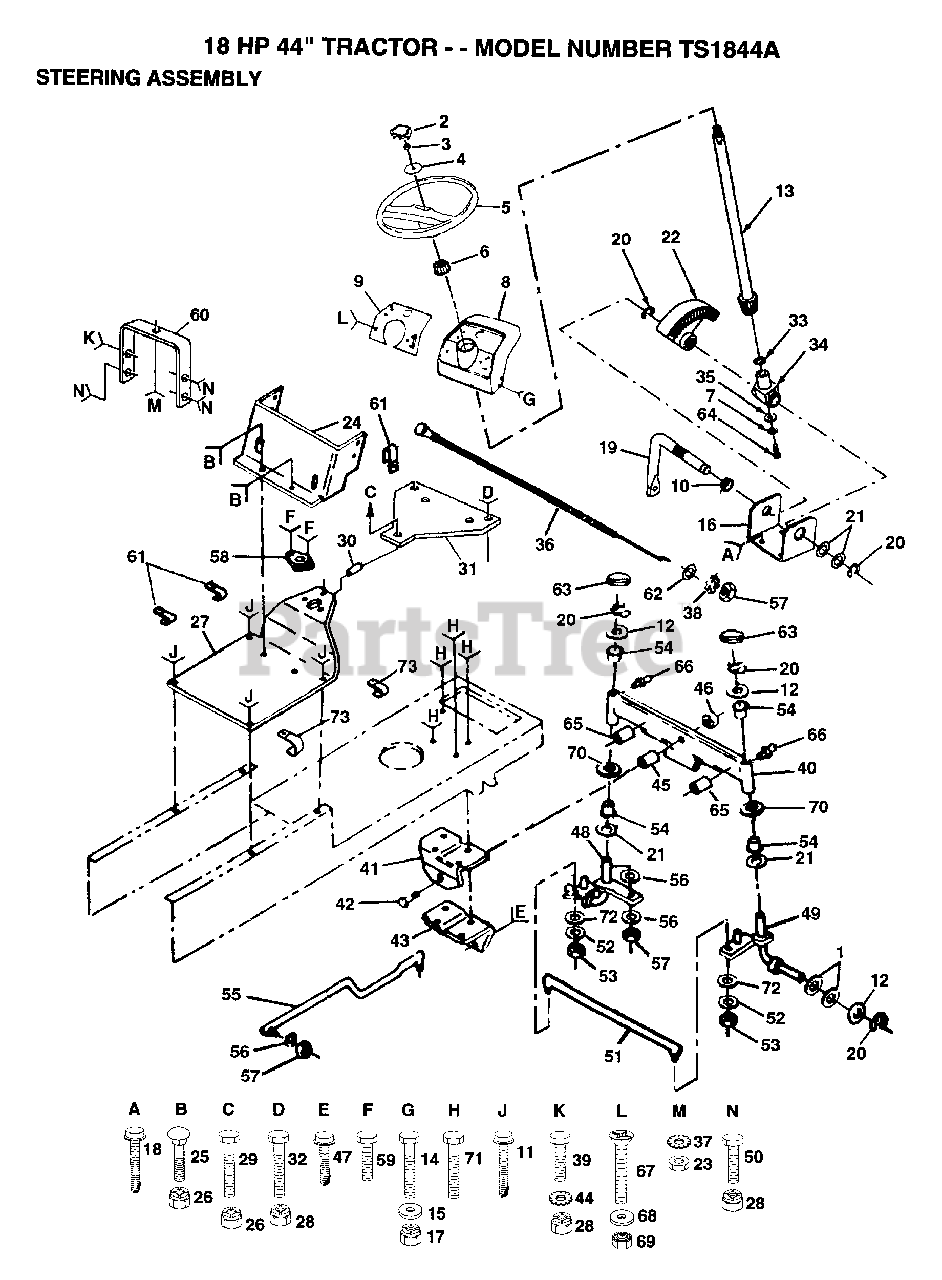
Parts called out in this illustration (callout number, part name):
1	WASHER
2	"INSERT,STR WHEEL"
4	WASHER
6	ADAPTER LT
7	LOCKWASHER
9	PLATE.DASH.SLKSCR
10	NYLINER T
11	SCREW LT
12	WASHER
14	BOLT
15	WASHER
16	"BRKT,STEERING"
18	SCREW
20	RING
21	WASHER .T
22	GEAR SECTOR
24	LOWER DASH
25	SCREW
27	SADDLE.YT.GOOSE N
29	BOLT
30	SPACER
33	THRUST WASHER
34	SUPPORT.SHAFT
36	CHOKE CONTROL
38	LOCKWASHER
39	BOLT
40	FRONT AXLE
41	SUPPORT-SADDL T
42	BOLT LT
43	SUPPORT.SADDLE.FT
44	LOCKWASHER
45	BEARING
46	"NUT-LOC,FLANGE LT"
47	SCREW LT
48	SPINDLE LH
49	SPINDLE RH
51	TIE ROD
52	LOCKWASHER
53	NUT.LOCK.5/16-24
54	COL. SRTG. BEAR.
56	LOCKWASHER
60	SUPPORT ASS'Y
61	CLIP T
62	WASHER
63	CAP
64	"SCREW,SPECIAL"
65	AXLE PIN
66	ZERK M
67	SCREW
68	WASHER
70	WASHER
71	SCREW SPECIAL
72	WASHER M
73	"CLIP,INSULATOR"
